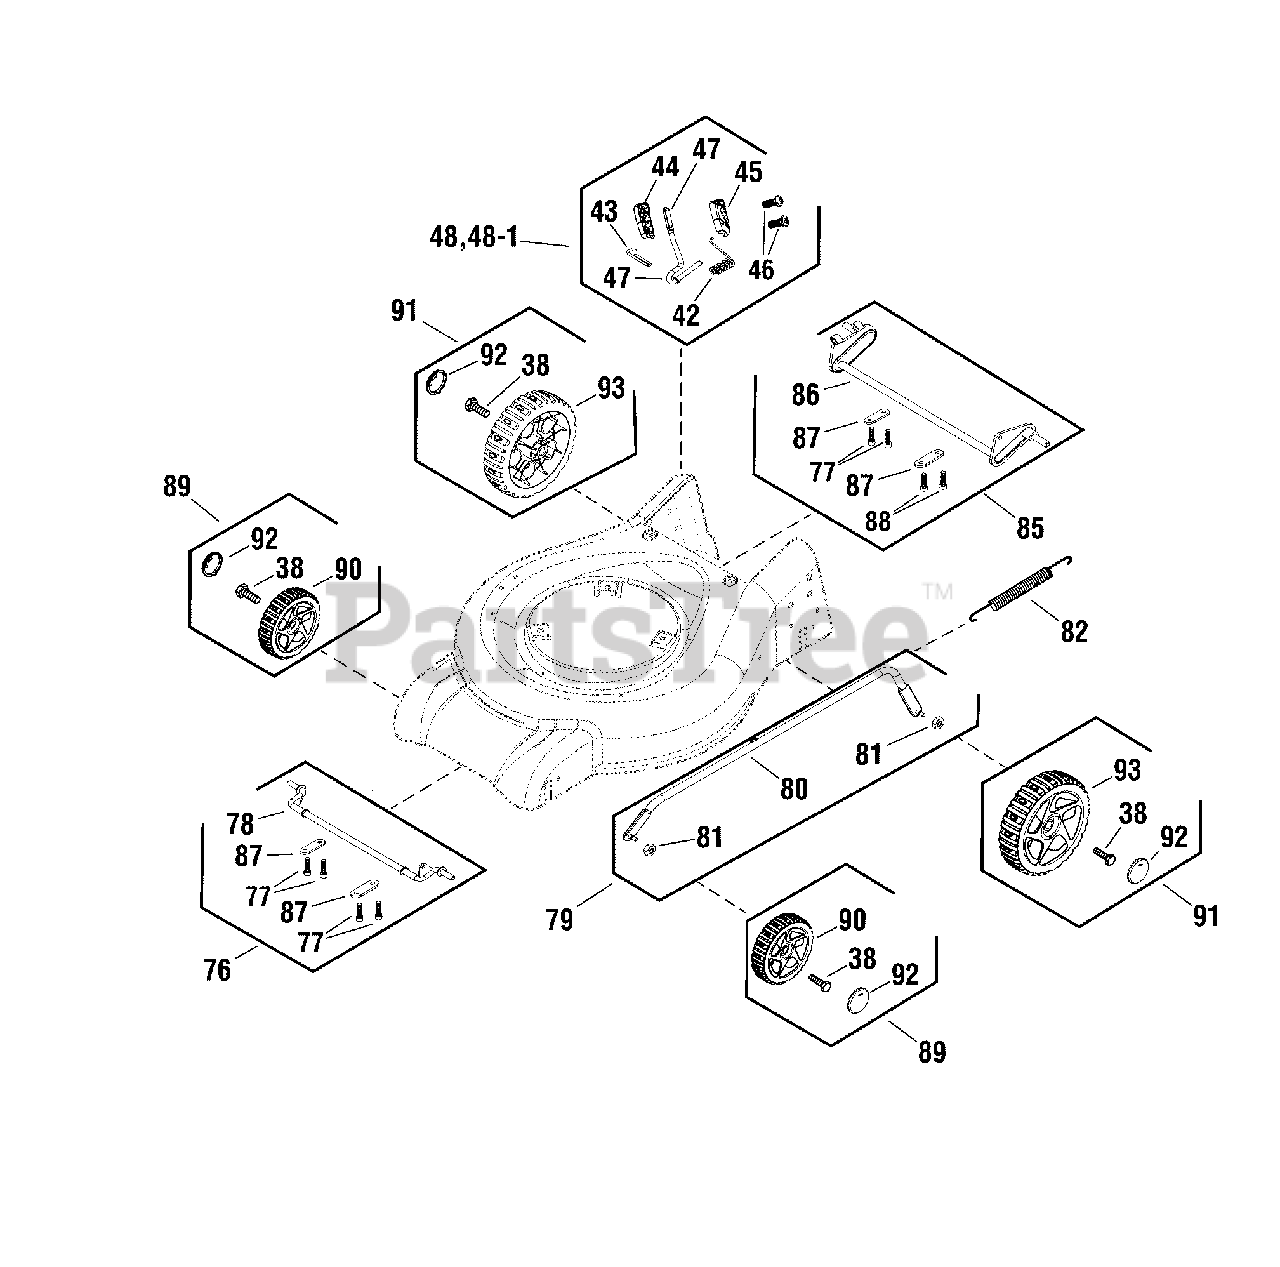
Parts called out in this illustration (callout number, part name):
38	BOLT
42	SPRING
43	PIN, Cotter
44	HOUSING, Left
45	HOUSING, Right
47	ROD, Adjusting
48	KIT, Handle, Height Adjust
48-1	KIT, Handle, Height Adjust, EU
76	KIT, Front Axle
78	AXLE, Front
79	KIT, Rod, Height Adjust, NA & EU
80	ROD, Height Adjust
81	NUT
82	KIT, Spring
85	KIT, Rear Axle
86	SHAFT
87	TAB
89	KIT, Wheel, 8"
91	KIT, Wheel, 10", NA & EU
92	COVER, Wheel
